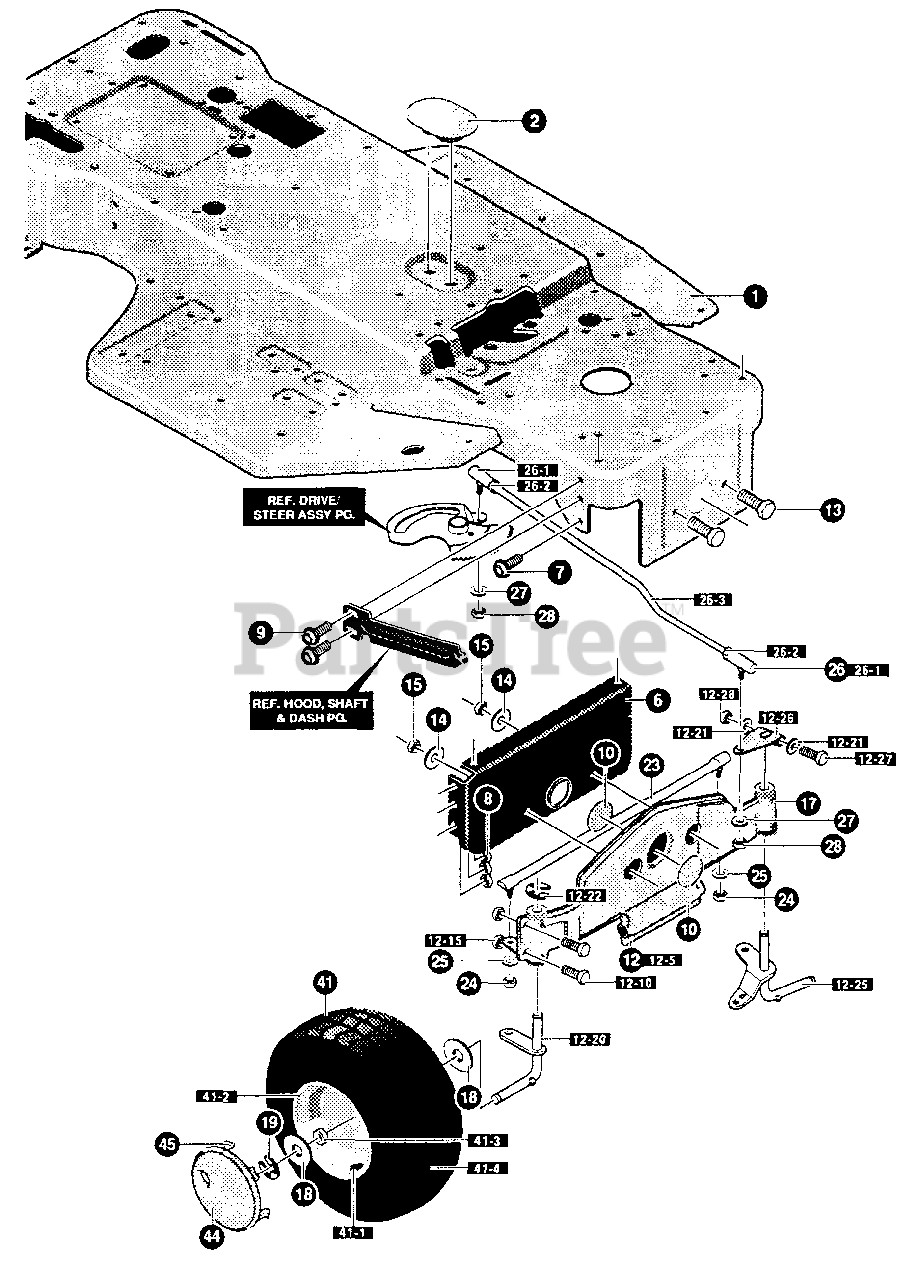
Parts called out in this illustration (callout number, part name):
1	FRAME, EURO
2	COVER,SECTOR BOLT PLAS GREY
6	BRACKET, FRONT AXLE SUPPORT
7	SCREW, 5/16-18X.75WDFLLK
8	NUT, 5/16-18 HXWDFLLK
9	SCREW, 5/16-18X.75 HXWDFL
10	PLUG,FRONT AXLE 1.938DIAX.062"
12	SUB-ASSY FR AX ERO LT SHORT
12-5	AXLE,ASSY FRONT WELD BLK
12-10	SCREW, 5/16-18X.75 HHC
12-15	NUT, 5/16-18 REGHEXCTRLK
12-20	ASSY SPDLE RH EROLT
12-21	WASHER, FLAT .391X1.00X.125
12-22	RING, RETEX.57X.05TRU5133-75
12-25	ASSY SPDLE LH EROLT
12-26	ARM STEERING UPPER BLACK
12-27	SCREW, 3/8-16X2.50 HHC
12-28	NUT, 3/8-16 REGHXCTRLK
13	SCREW, 3/8-16X3.00 HHC
14	WASHER .39IDX1.25DX.07 BELLVIL
15	NUT, 3/8-16 REGHXCTRLK
17	ZERK, GREASE FITTING
18	WASHER, FLAT .755X1.31X.075
19	RING, RETEX .57X.05TRU5133-75
23	TIE ROD.625DIA GRND ENGAGER
24	NUT, 3/8-24 REGHEX
25	WASHER, REGSPTLK.393X.68X.10
26	LINK, ASSY,625DIA DRAG LT 4WS
26-1	BALL JOINT 3/8 THD SHORT STUD
26-2	NUT, 3/8-24 REGHEXJAM
26-3	LINK, .625DIA DRAG LT 4WS
27	WASHER, REGSPTLK.393X.68X.10
28	NUT, 3/8-24 REGHEXJAM
41	TIRE & RIM, PU 15X6.OX6 WHI
41-1	VALVE STEM
41-2	RIM, WHEEL
41-3	BEARING, FL
41-4	TIRE 15X6.00X6
44	HUBCAP, 6" EURO GREY
45	CLIP,HUBCAP TINN #C25467-017-4
